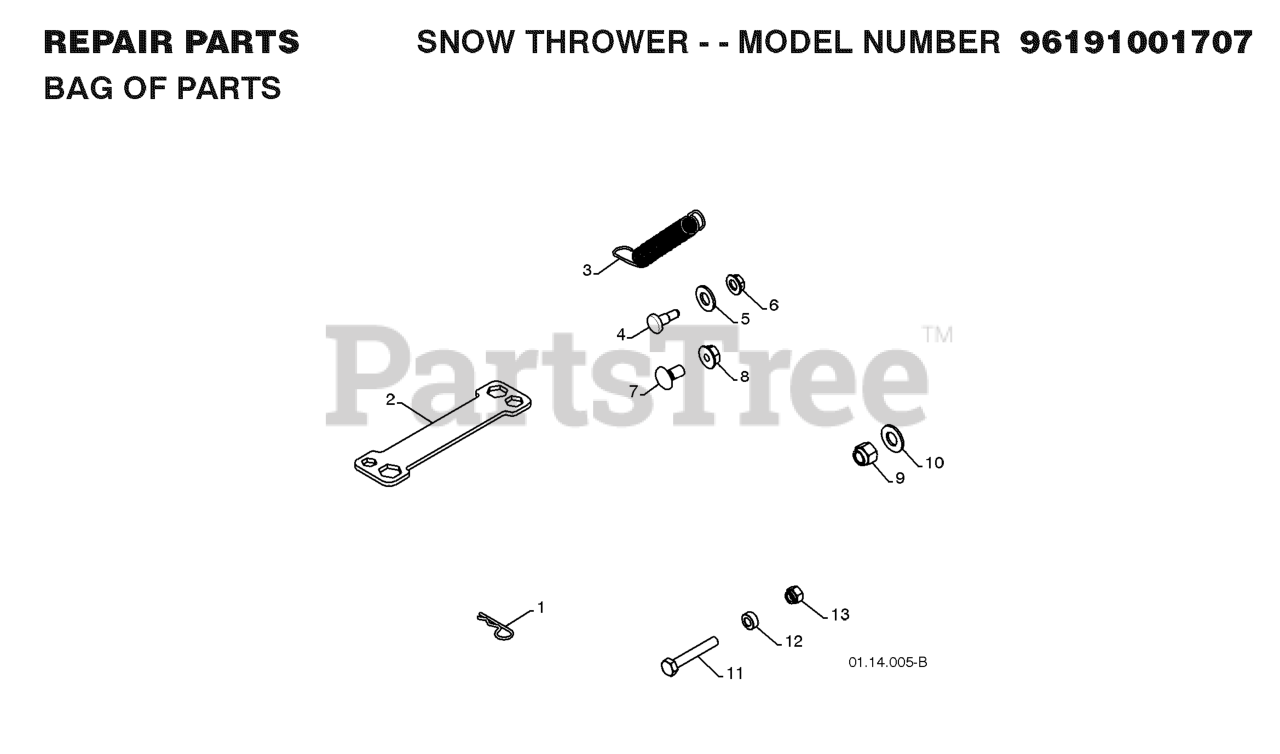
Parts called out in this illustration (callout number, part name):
1	SPRING RETAINER
2	RP WRENCH, SNOWTHROWER
3	SPRING.DEFLECTOR.REM.CHUTE
4	BOLT, SHOULDER
5	WASHER, NYLON FRICTION
6	NUT.HEX.FLANGE.1/4
7	BOLT
8	NUT.LOCK.5/16-18
9	NUT
10	WASHER
11	BOLT, SHEAR
12	SPACER.3943.SLEEVE.250X.47
13	LOCKNUT.NYLOC.1/4-20
